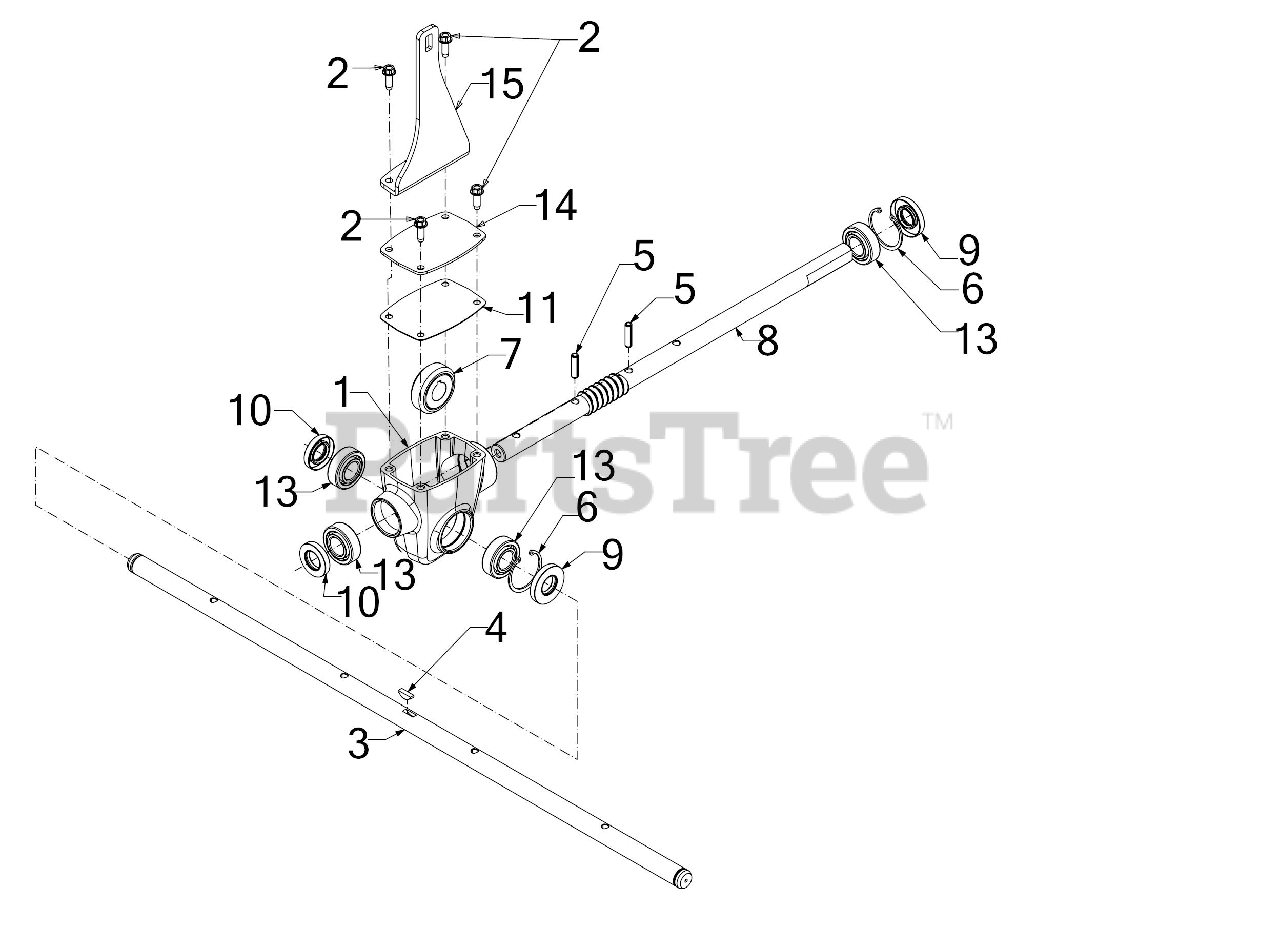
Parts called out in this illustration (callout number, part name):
1	AUGER GEARBOX HOUSING
2	SCREW 1/4-20 x .750
3	30" AUGER AXLE
4	KEY-3/16 x 5/8
7	WORM GEAR 20T
8	WORM SHAFT .75OD
11	GEARBOX COVER GASKET
13	BALL BEARING
14	GEARBOX COVER
15	GEARBOX SUPPORT BRACKET
